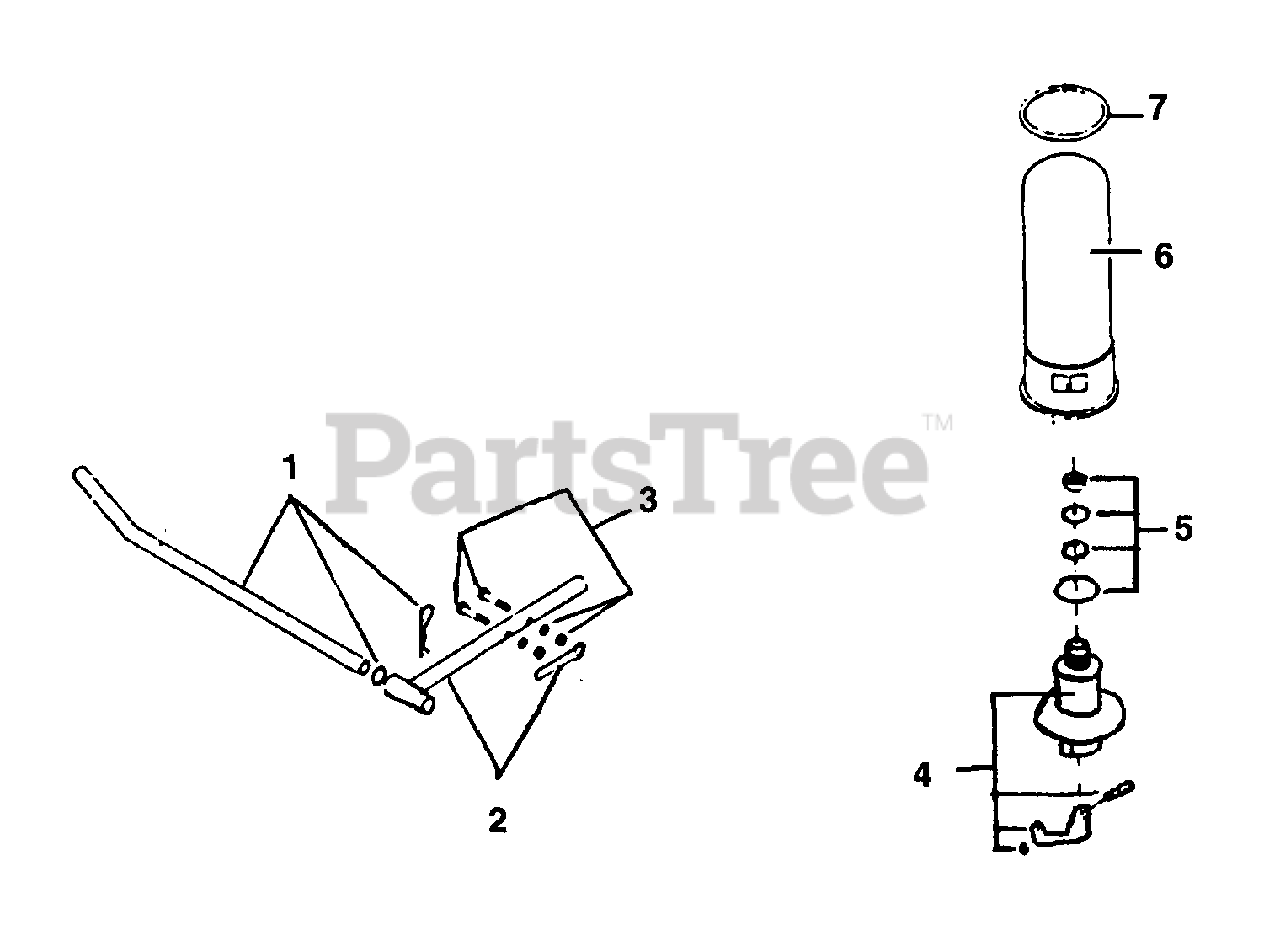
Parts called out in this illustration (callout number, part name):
1	PUMP HANDLE
2	ARM, PUMP HANDLE
3	HARDWARE KIT, HANDLE
4	PUMP MODULE ASSY.
5	"O" RING SET, PUMP MODULE
6	PRESSURE TANK
7	"O" RING, PRESSURE TANK
